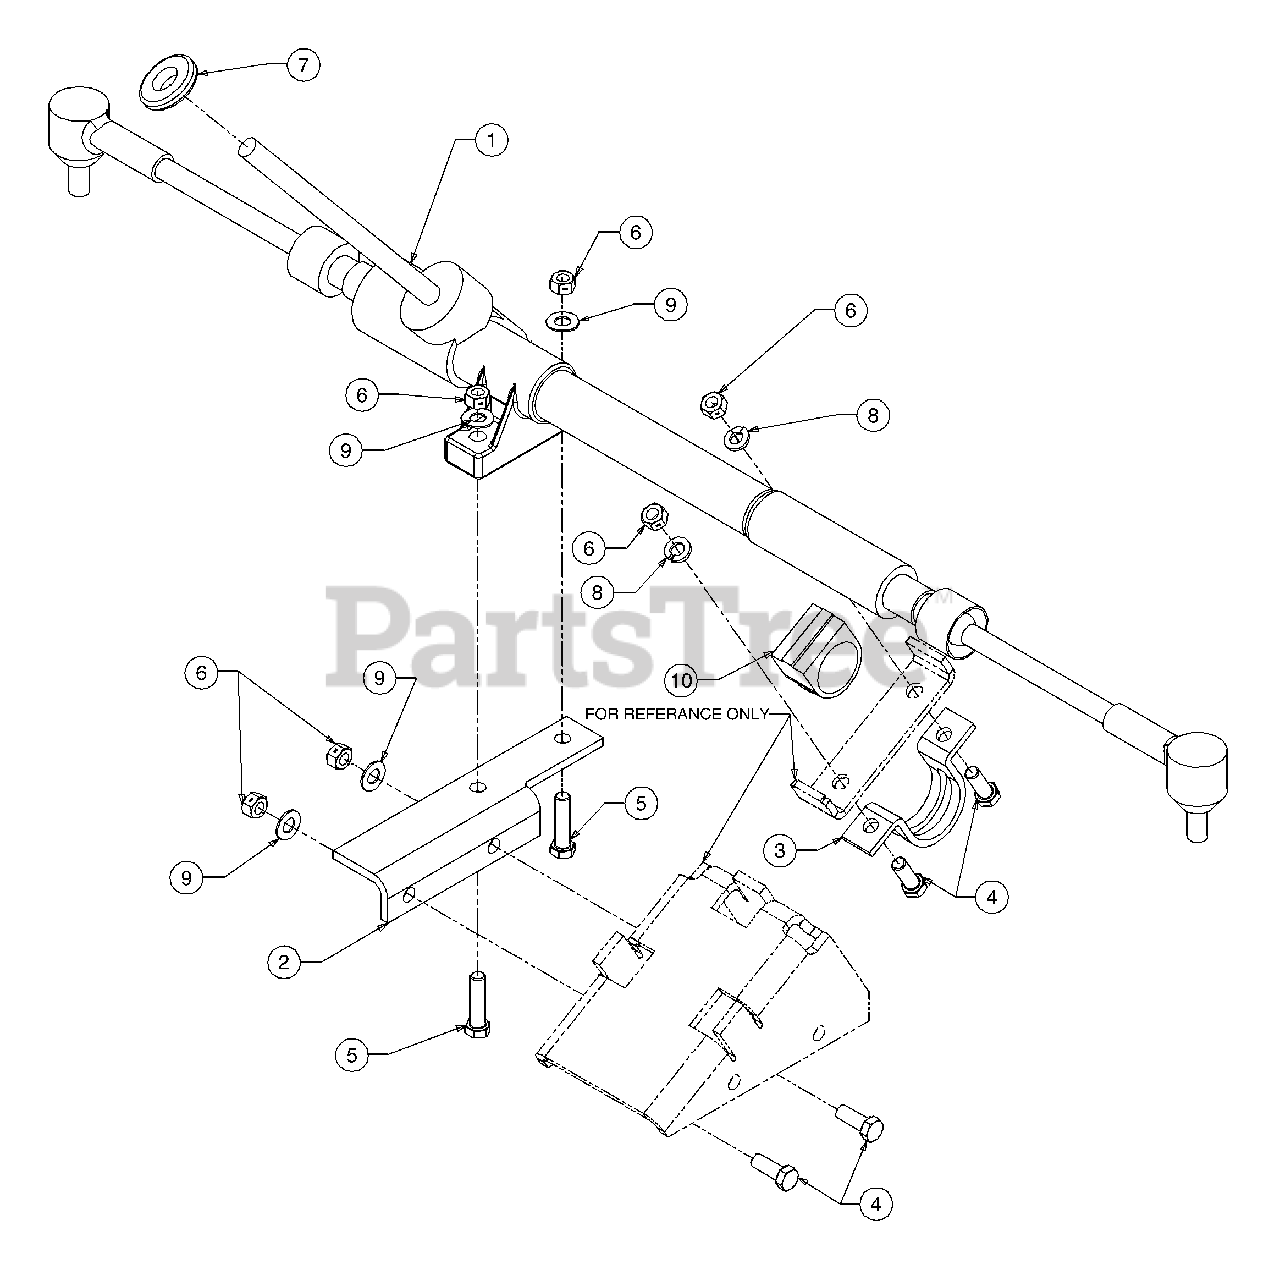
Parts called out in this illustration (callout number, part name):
1	Gear Assembly, Steering
2	Steering Bracket, Sector Clamp
3	Bracket, Steering Mounting
4	Hex Screw, 3/8-16, 1.00, Gr5
5	Hex Screw, 3/8-16, 1.50, Gr5
6	Nut, Hex Lock, 3/8-16
7	Grommet, Steering Shaft
8	Washer, Lock, 3/8
9	Washer, Flat, .406 x .812 x .051
10	Bushing, Rubber
